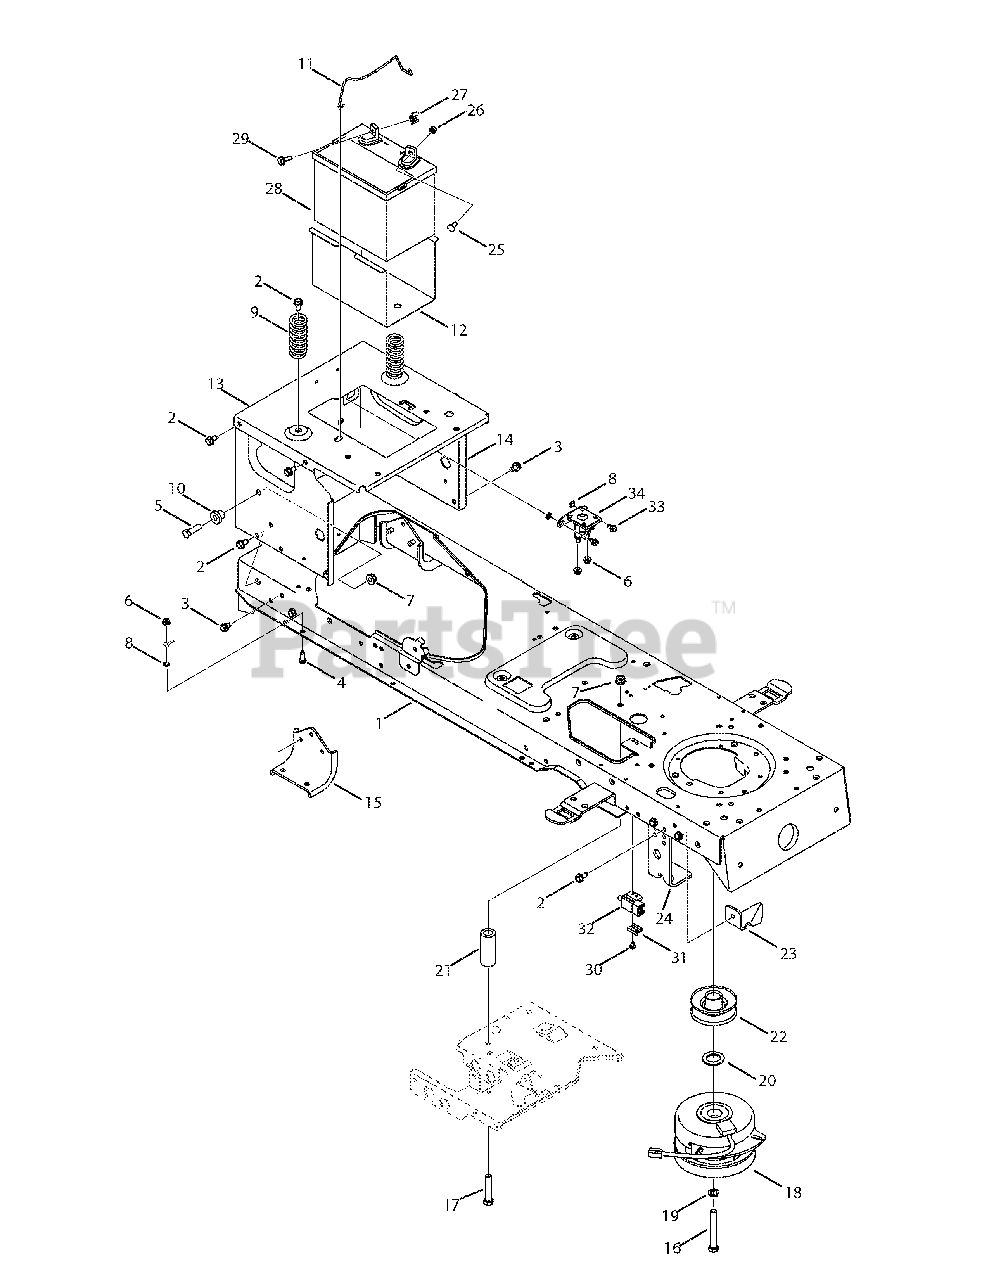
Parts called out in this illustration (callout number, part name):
3	Screw, 5/16-18, 0.500
4	Screw, 1/4-20, 0.750
5	Screw, 3/8-16, 1.25, Gr5
6	Nut, Flange Lock, 1/4-20
7	Nut, Flange Lock, 3/8-16
8	Washer, Lock, 1/4, External
9	Spring, Compress., 1.28 x 3.125
10	Spacer, Shoulder,.38 x 1.0 x.70
11	Hold Rod, Battery
16	Screw, 7/16-20, 3.50, Gr5, Lock
17	Screw, 3/8-16, 2.25, Gr5
18	PTO Clutch, Electric
19	Lock Washer, 7/16
20	Washer, Flat, 1.031 x 1.620 x.095
21	Spacer,.385 ID x.635 OD x 1.54
22	Pulley, Engine, 3.56 Diameter
25	Hex Flange Bolt, 1/4-20,.75
26	Nut, Sems, 1/4-20
27	Nut, Wing, 1/4-20
28	Battery, 235 CCA
29	Screw, Shoulder,.250 x.15, 1/4-20
30	AB Screw, #10-16 x.500
31	Switch Plate
32	Switch
33	Screw, 1/4-20, 0.50
34	Solenoid, 12V, 100 Amp
